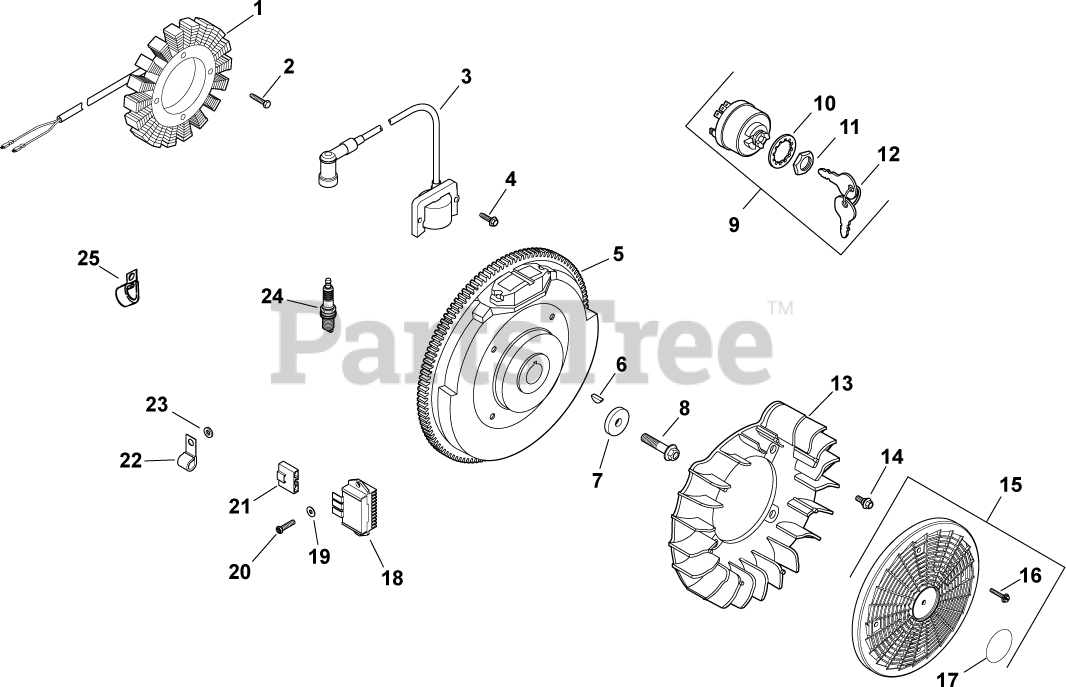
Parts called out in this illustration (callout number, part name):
1	KIT, 15 / 20 AMP STATOR
2	SCREW, M5X0.8X25 - (#25086402S)
3	KIT, MODULE IGNTN (CDI FIXED)
4	SCREW, FLG THD FRM M5X.8X20-(#25086399S)
5	FLYWHEEL, PAINTED-USE 24 025 59-S
6	KEY, 3/16" X 5/8"
7	WASHER, FLAT 13/32"
8	SCREW, FLG M10X1.5X45 - (#25086361S)
9	SWITCH ASSY, KEY (KM)-USE 25 099 32-S
10	WASHER, INTERNAL TOOTH
11	NUT, KEY SWITCH
12	KEY, SET -USE 48 340 01-S
13	FAN USE 24 755 253-S
14	BOLT, SHOULDER
15	KIT, GRASS SCREEN
16	SCREW, FLG SEMS M4X.7X25
17	DECAL, GRASS SCREEN USE 24 113 499-S
18	REG/RECTIFIER (20/25 AMP)-USE 25 403 20-
19	WASHER, FLAT 7/32"
20	SCREW, PHL HD #11-16X7/8"
21	CONNECTOR, BODY (KM)-USE 25 155 41-S
22	CLIP, CABLE
23	WASHER, FLAT 1/4" (O.D. 1/2")
24	PLUG, SPARK (STD)
25	CLIP, CABLE - USE 24 154 10-S
